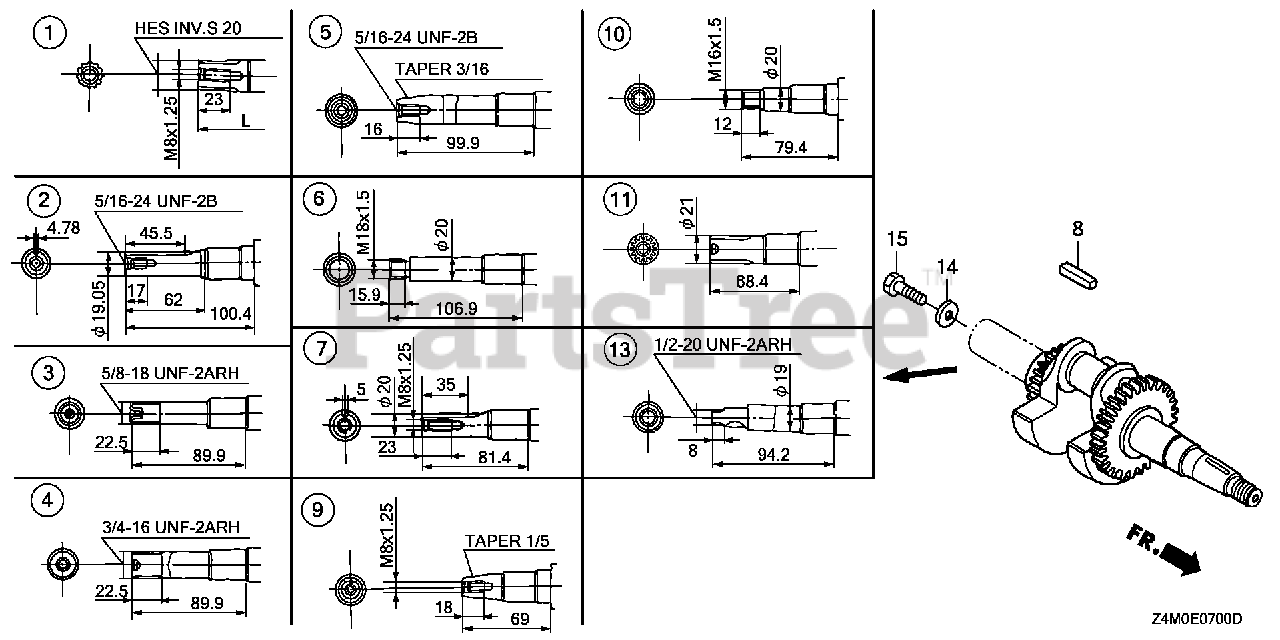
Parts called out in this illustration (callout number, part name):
7	CRANKSHAFT
8	KEY (5X5X33)
14	WASHER (8MM)
15	BOLT, HEX. (8X25)
